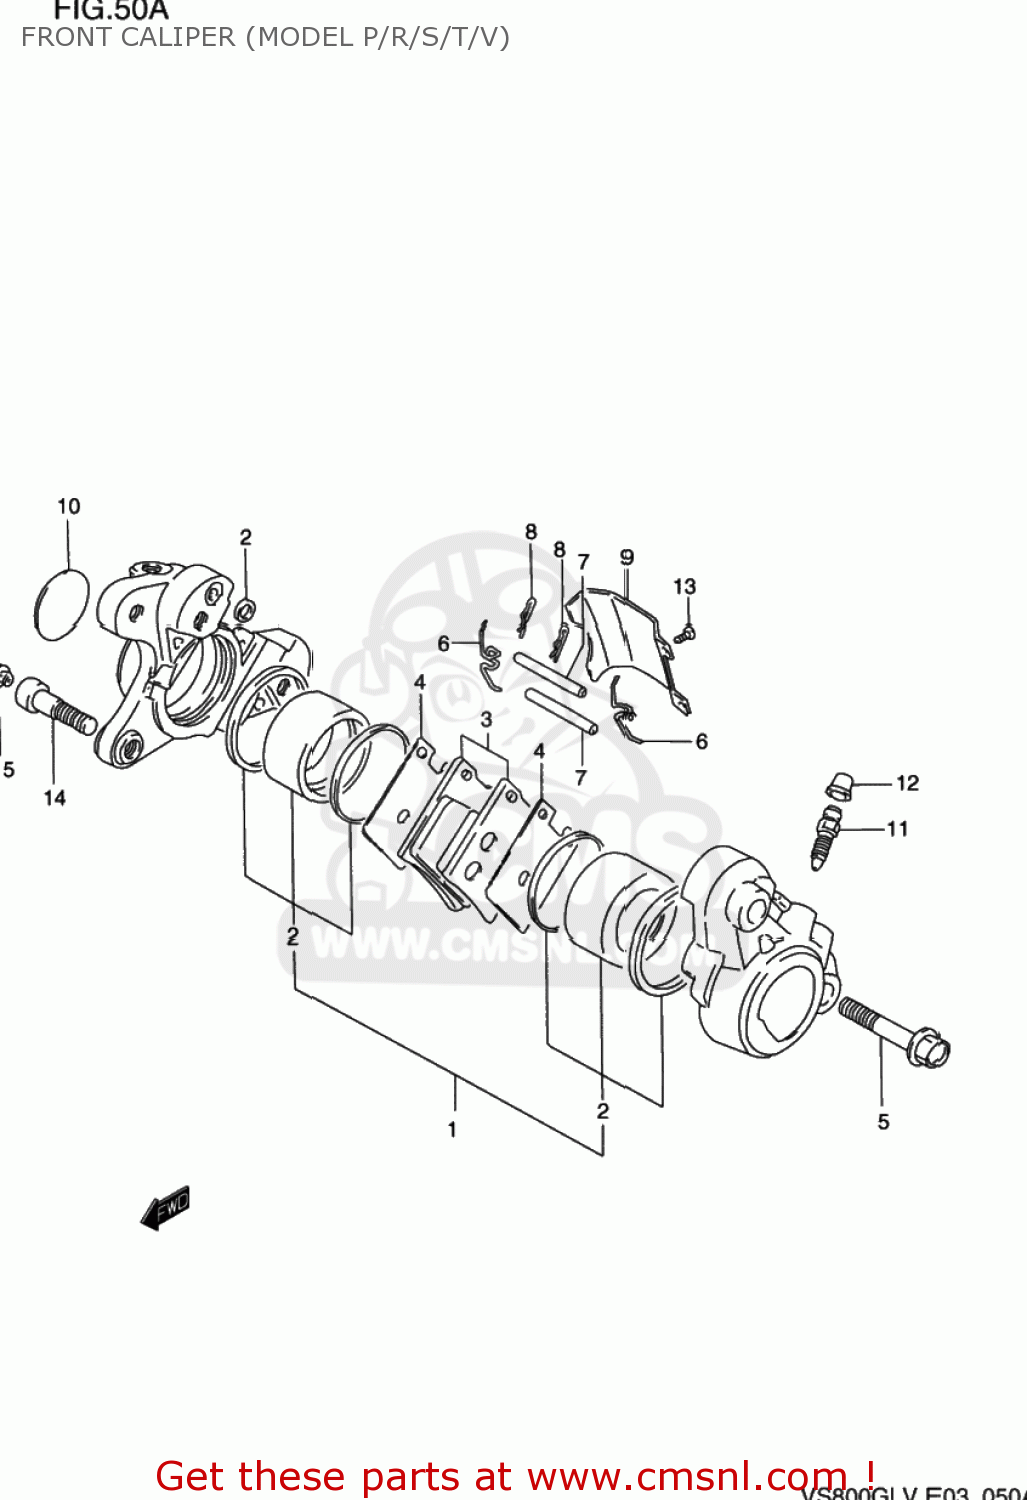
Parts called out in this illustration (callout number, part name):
1	PISTON SET
2	SEAL SET,PISTON
3	PAD SET (NAS)
4	SHIM,PAD
5	BOLT,HOUSING
6	SPRING
7	PIN,PAD
8	CLIP,PAD PIN
9	COVER,CALIPER
10	CAP,CALIPER
11	BLEEDER
12	CAP,BLEEDER PLUG
13	SCREW,CALIPER COVER (4X
14	BOLT(10X33)
15	CAP(OD:12)
